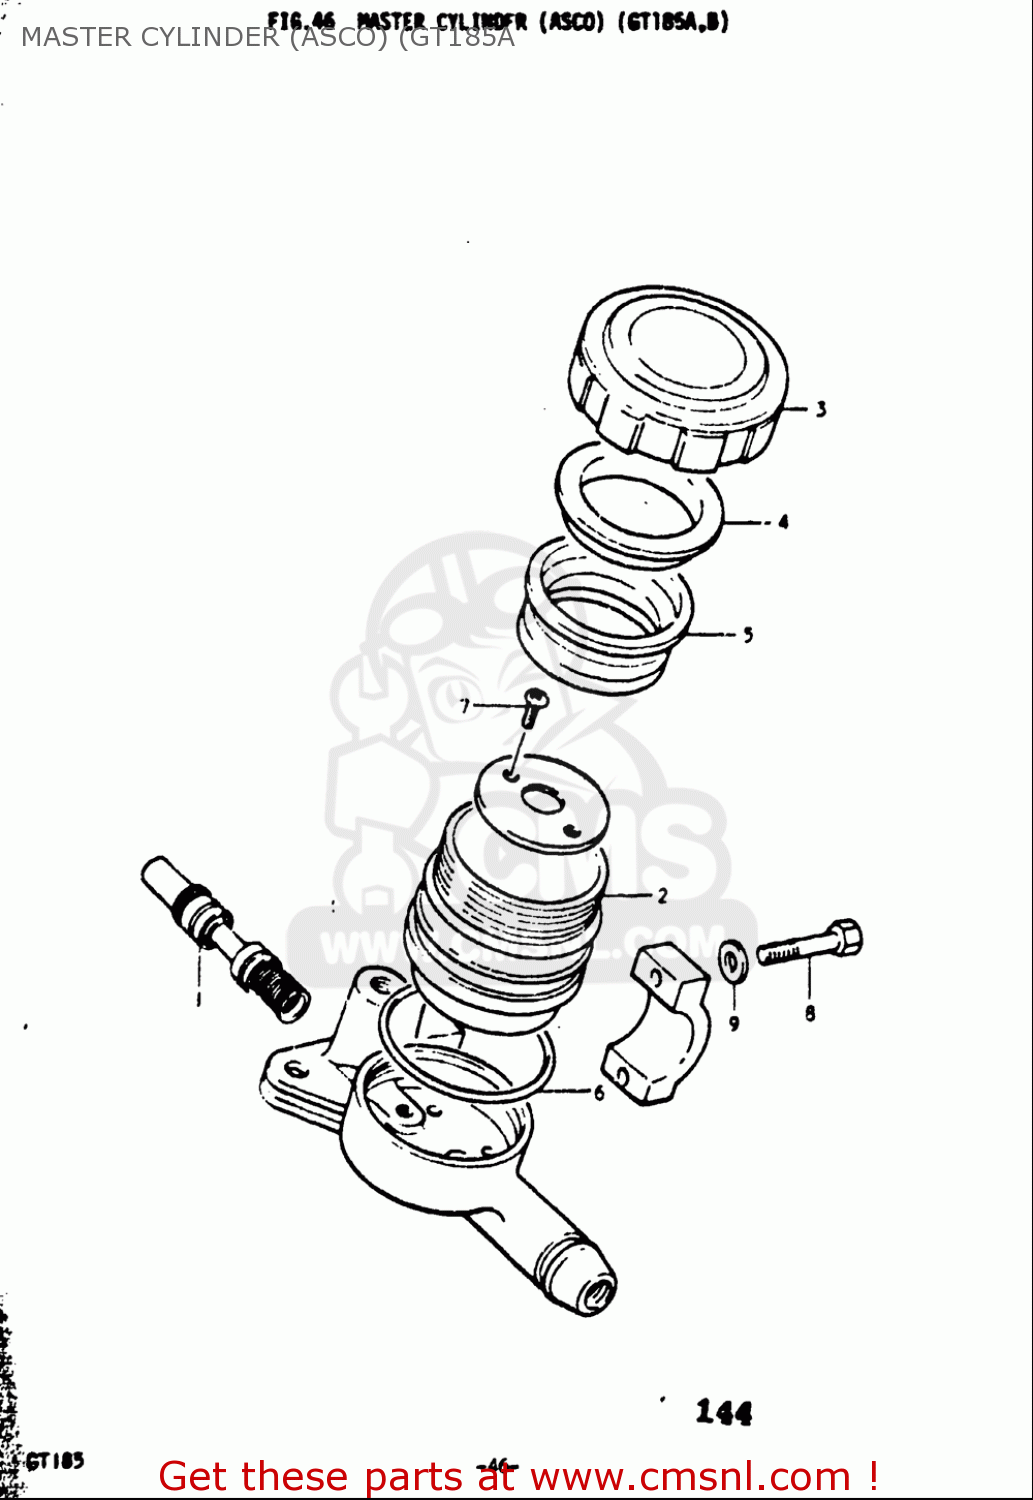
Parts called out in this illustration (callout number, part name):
1	PISTON & CUP SET
2	RESERVOIR
4	PLATE
5	DIAPHRAGM
6	O RING
8	BOLT
9	WASHER
